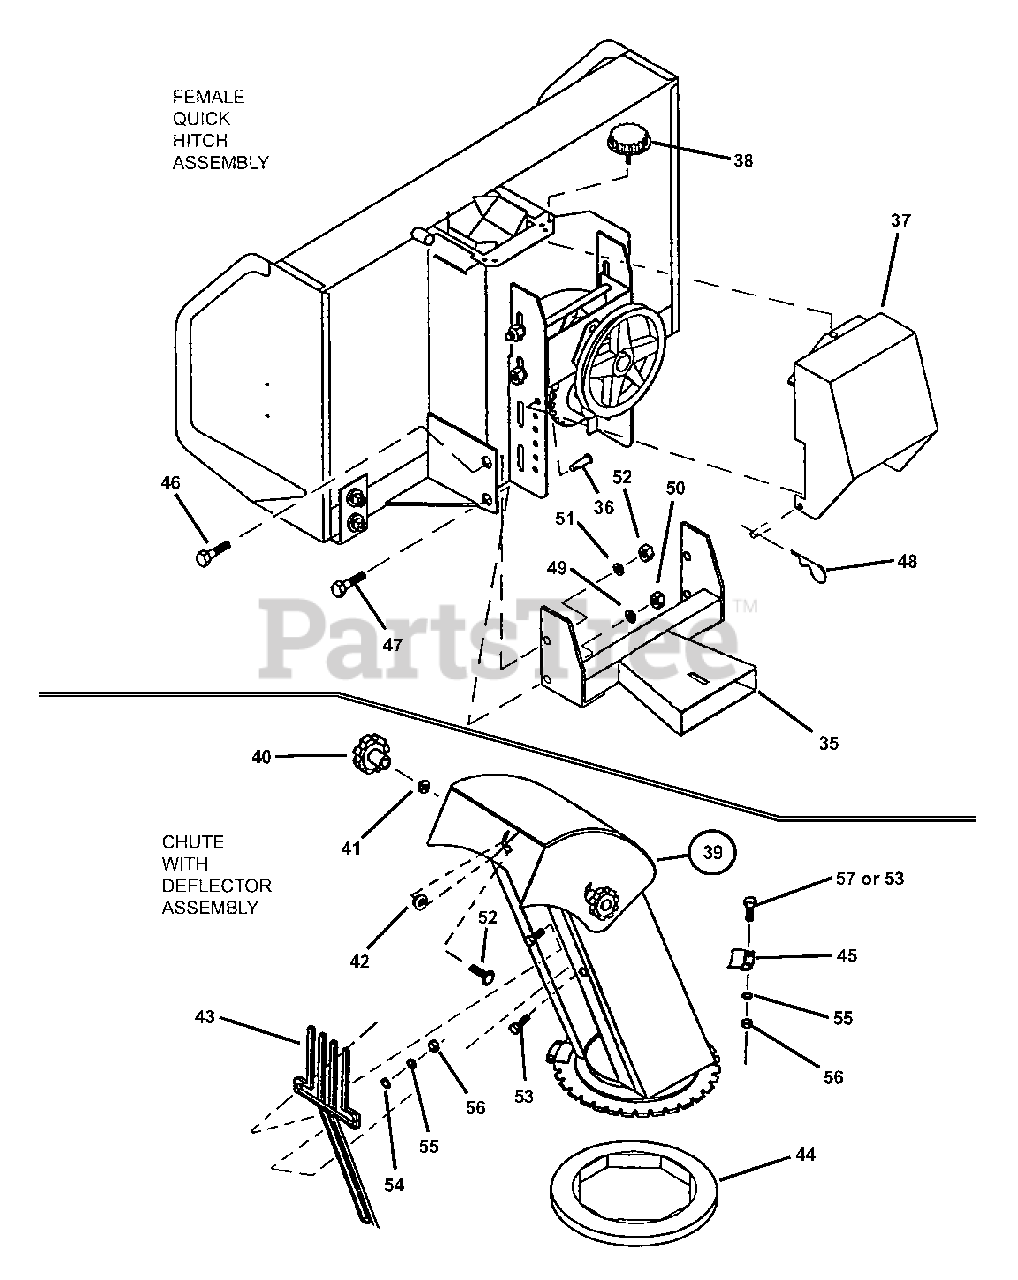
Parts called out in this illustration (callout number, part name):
35	HITCH, Female Quick
36	PIN, 1/4" Dia. x 1/2"
37	GUARD, Belt
38	KNOB, 5/16-18
39	ASSEMBLY, Chute, Base Knobs & Decal
40	KNOB, 5/16-18
41	WASHER, 11/32" Flat (nylon)
42	WASHER, 7/16" Flat (nylon)
43	HAND GUARD
44	RING, Nylon
45	PLATE, Retaining
46	BOLT, 3/8-16 x 1" Hex, Grade 5
47	BOLT, 1/2-13 x 1" Hex, Grade 5
48	HAIR PIN, 2mm x 41 mm
49	WASHER, 1/2" Lock
50	NUT, 1/2-13 Hex
51	WASHER, 3/8" Lock
52	BOLT, 5/16-18 x 1-1/2" Square Neck Carriage
53	BOLT, 1/4-20 x 3/4" Hex
54	WASHER, 5/16" Flat
55	WASHER, 1/4" Lock
56	NUT, 1/4-20 Hex, Grade 5 or B
57	BOLT, 1/4-20 x 1/2" Hex
